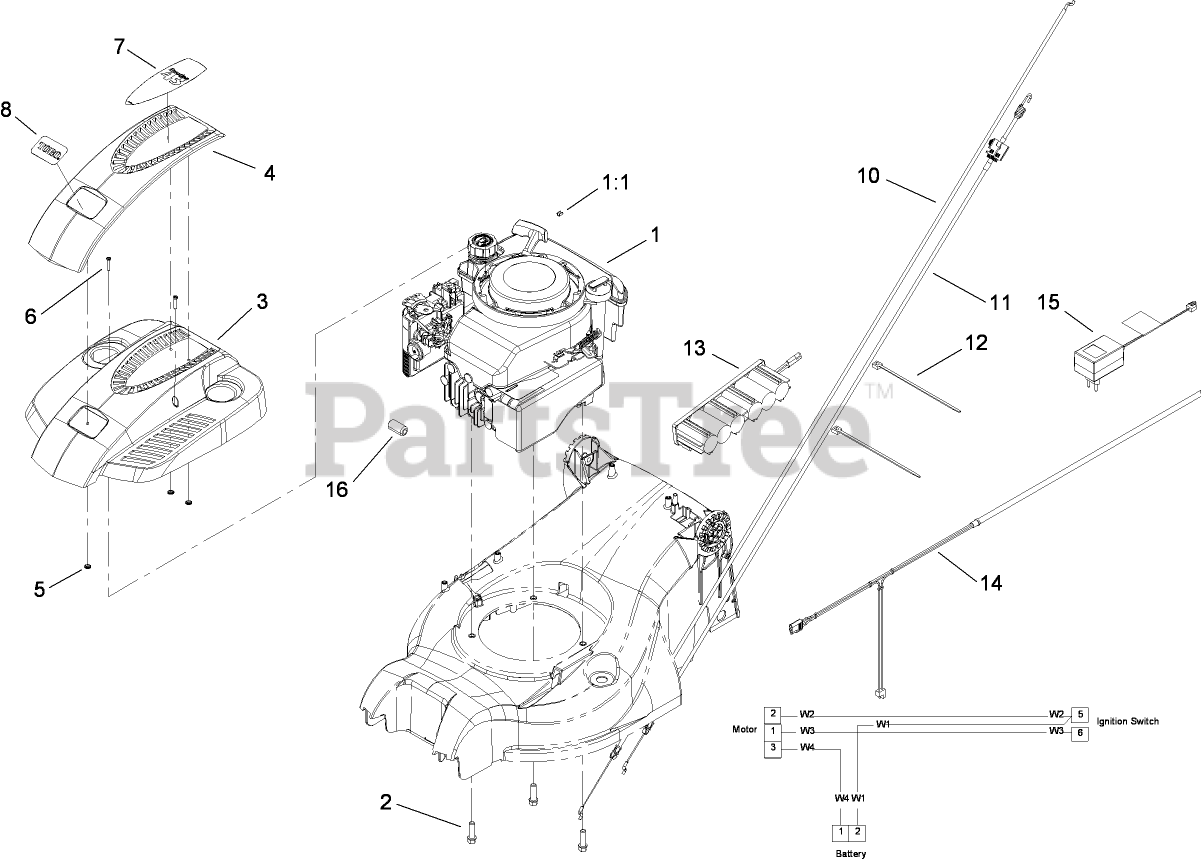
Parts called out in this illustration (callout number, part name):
1	Loose Parts Package
1:1	STOP-ROPE
2	SCREW-TAPTITE
3	SHROUD-ENGINE
4	COVER-SHROUD
5	CLIP-PUSH
6	SCREW-PPH
12	TIE-CABLE
13	BATTERY-WET
14	HARNESS-WIRING
15	CHARGER-EUROPEAN, 12V DC
16	FERRITE-SNAP ON
